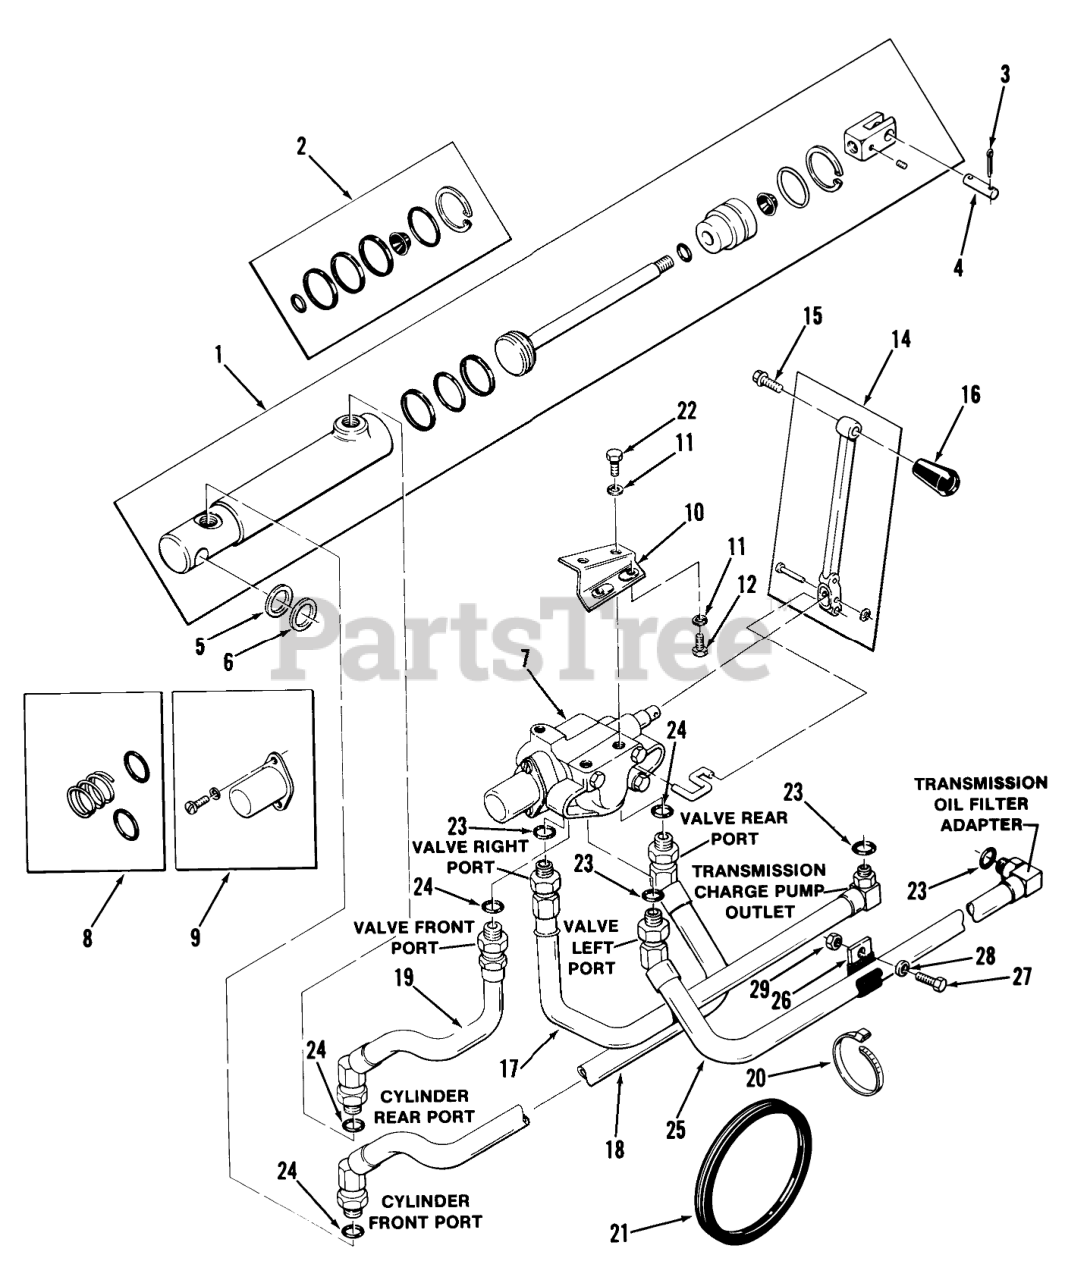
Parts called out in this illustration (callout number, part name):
1	Hydraulic Cylinder
2	S/A O-RING&GASKET AS
4	PIN
5	WASHER
6	Spacer
7	Hydraulic Valve
8	0-Ring Kit-S.A.
9	Spool Cap Kit
10	Mounting Bracket
11	Lockwasher
12	Bolt
13	Lockwasher
14	S/A HANDLE&HARDWARE
15	SCREW
17	ASSY-HYDRAULIC HOSE
18	Hose-Valve To Cylinder
19	Hose-Valve To Cylinder
20	PLASTIC TIE
21	GROMMET
22	Bolt
23	0-Ring
24	O RING
25	ASSY-HYD HOSE
26	CLIP
27	H H C S
29	Nut
